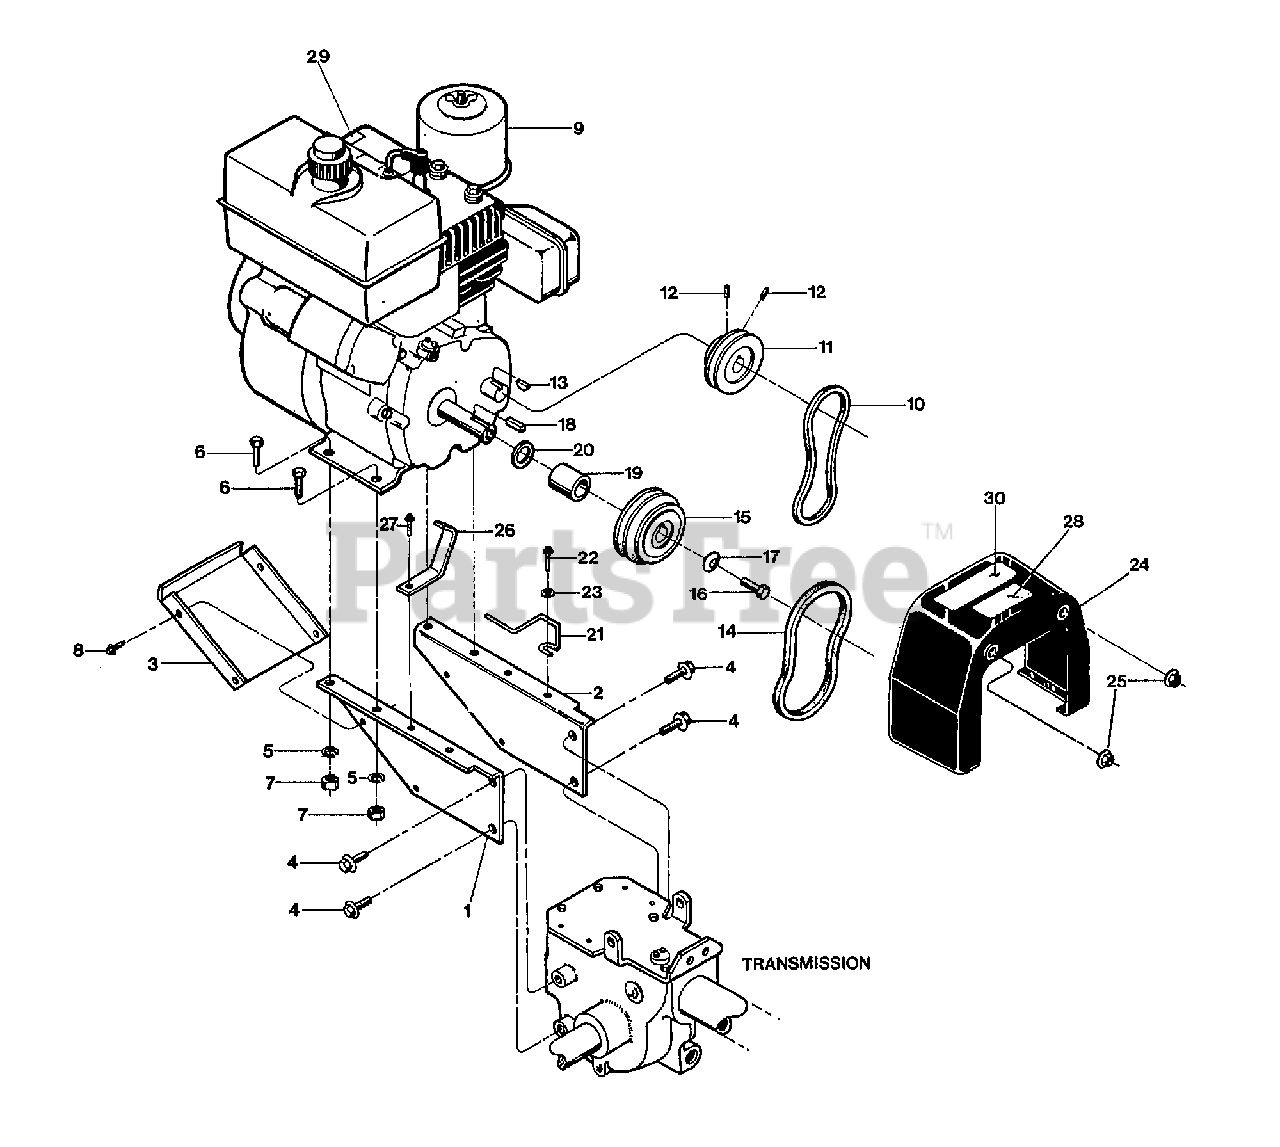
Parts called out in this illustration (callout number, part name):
1	BRKT-ENG LT P4
2	BRKT-ENG RT PNT
3	PAN-ENG BRKT PNT
4	SCR-HFLK 5/16-18X.75 ZP
5	WASHER-LK .312 ZP
6	SCR-HHC 5/16-18X.75 GR 5 ZP
7	NUT-HEX 5/16-18 ZP
8	SCR-HW M10-32X.5 THRD ROLL
9	ENGINE, TECUMSEH, 6HP RECOIL START,
10	BELT-V REV DR ECONO (SEE V-BELT BELOW)
11	PULLEY-REV MACH
12	SCR-SS 1/4-20 X .25 (SECURES REVERSE ENGINE PULLEY)
13	KEY-WOODRUFF #5
14	BELT-V GROOVE FWD SMFRAME
15	PULLEY-ENGINE MACH
16	SCR-HH 3/8-24X1.0 G5 ZP
17	WASHER-.994X.413X.145
18	KEY-.188 SQX1.0
19	SPACER-.937X.755X.938
20	SHIM-1.0X.7656X.031
21	GUIDE-BELT FWD
22	SCR-HWH 1/4-20 X .75 STH
23	WASHER-FLAT 1/4 SAE
24	COVER-BELT W/DECALS (INCL. 28 & 30)
25	NUT-HFLK 5/16-18 ZP
26	GUIDE-BELT REV PNT
27	SCR-HWH 1/4-20 X .5 STH
28	DECAL-BELT POSITION
29	DECAL-STARTING STABIL
30	DECAL-BELT COVER OPC
